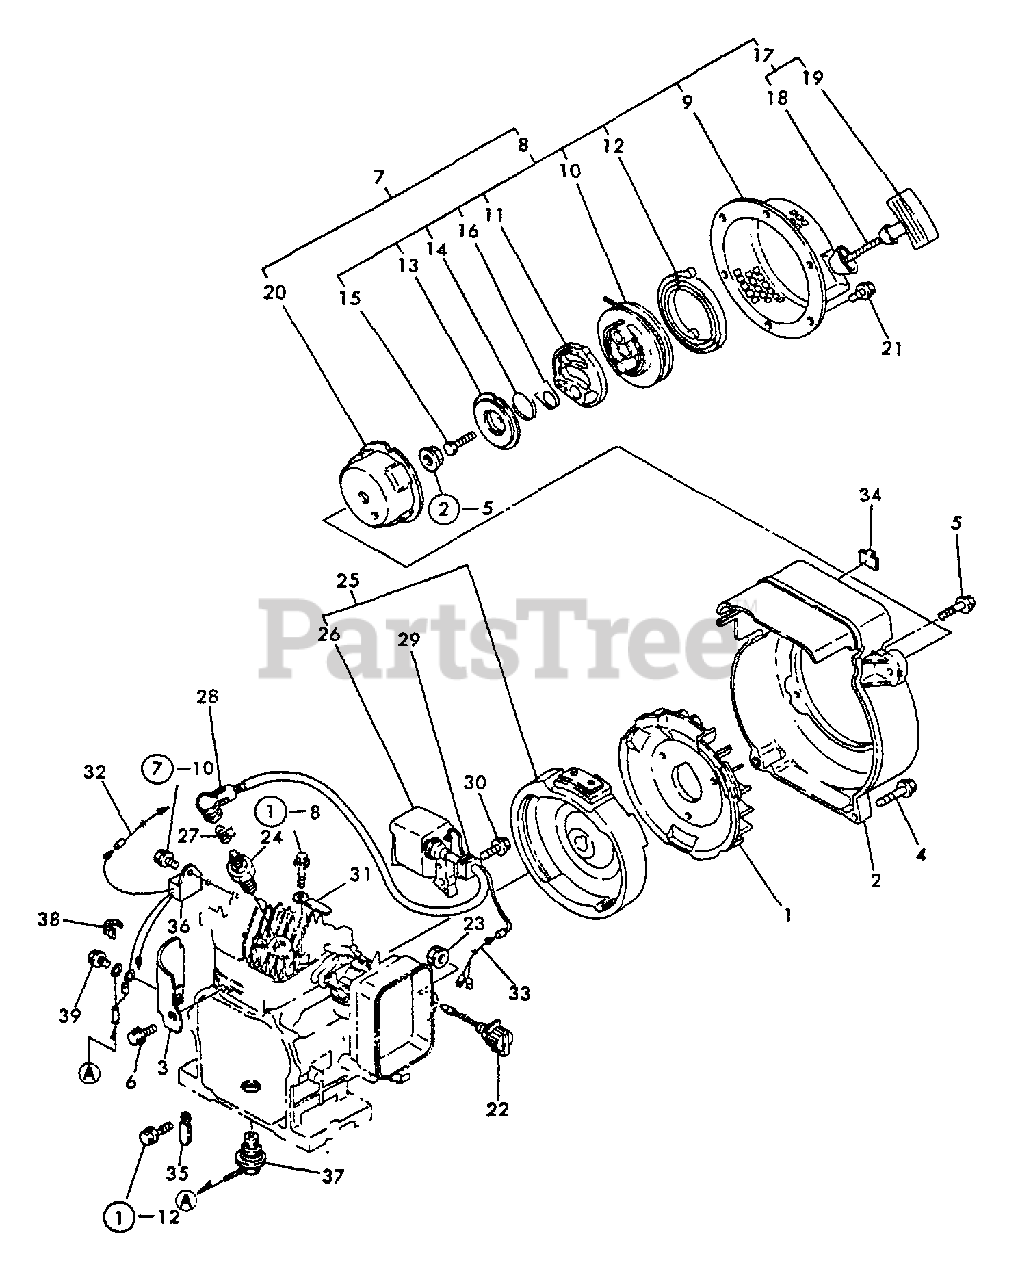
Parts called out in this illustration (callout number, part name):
1	FAN
2	COVER, FAN
3	SHIELD, CYLINDER
4	BOLT - 6X25
5	BOLT - 6X30
6	BOLT - 6X8 -- PLATED
7	STARTER ASSY
8	STARTER ASSY
9	STARTER CASE ASSY
10	REEL, ROPE
11	RATCHET
12	SPRING
13	PLATE, FRICTION
14	SPRING, FRICTION
15	BOLT
16	SPRING, RETURN
17	ROPE ASSY
18	ROPE
19	GRIP, STARTER
20	PULLEY, STARTER
21	BOLT - 6X8 -- PLATED
22	IGNITION SWITCH ASSY
23	NUT - 8
24	SPARK PLUG -- BPM-4A
25	FLYWHEEL MAGNETO ASSY
26	COIL, IGNITION
27	TERMINAL, SPARK PLUG CAP
28	CAP, SPARK PLUG
29	GROMMET
30	BOLT - 6X25
31	CLAMP
32	WIRE
33	WIRE
34	CLAMP
35	CLAMP
36	SENSOR, OIL
37	SENSOR, OIL LEVEL
38	CLAMP
39	BOLT - 6X8 -- PLATED
